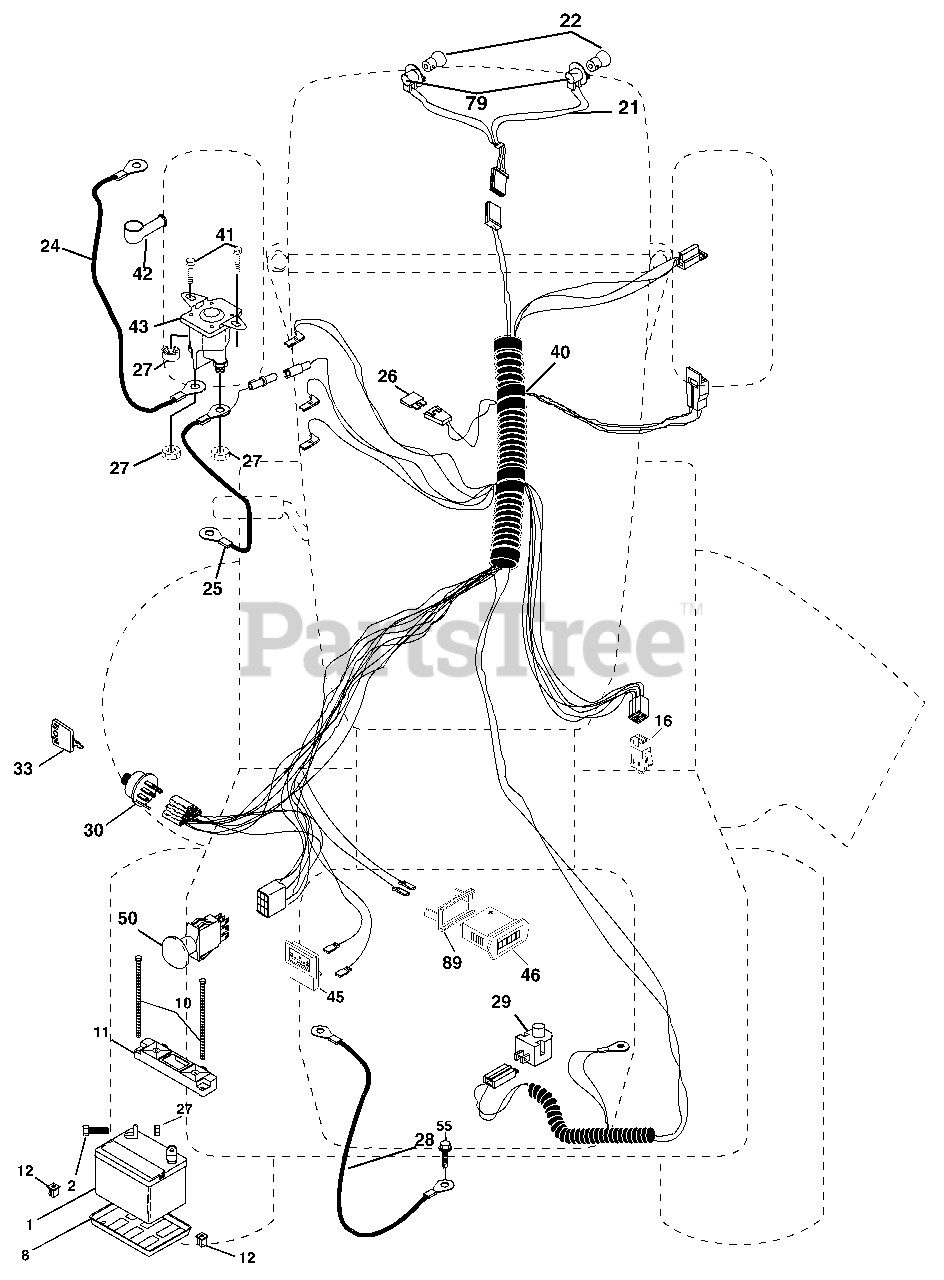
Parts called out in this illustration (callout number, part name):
1	Battery
2	Bolt, Hex 1/4-20 x 3/4
8	Tray, Battery
10	Bolt, Battery, Front 1/4-20 x 7-1/2
11	Holddown, Battery, Front
12	Nut, Push, Nylon, Battery, Front 1/4
16	Switch, Interlock
21	Harness, Light
22	Bulb Light #1156
24	Cable Starter
25	Cable
26	Fuse
27	Nut, Hex, Keps 1/4-20 unc
28	Cable, Ground
29	Switch, Seat
30	Switch, Ignition
33	Key
40	Harness, Ignition
41	Screw Thd Cut 1/4-20 x 1/2
42	Cover Terminal
43	Solinoid w/brass plunger
45	Ammeter
46	Hourmeter
50	Switch, PTO
55	Screw, Thd. Roll. 5/16-18 x 1/2
79	Socket Asm Bulb Twistlock
89	Bracket Snap-in
